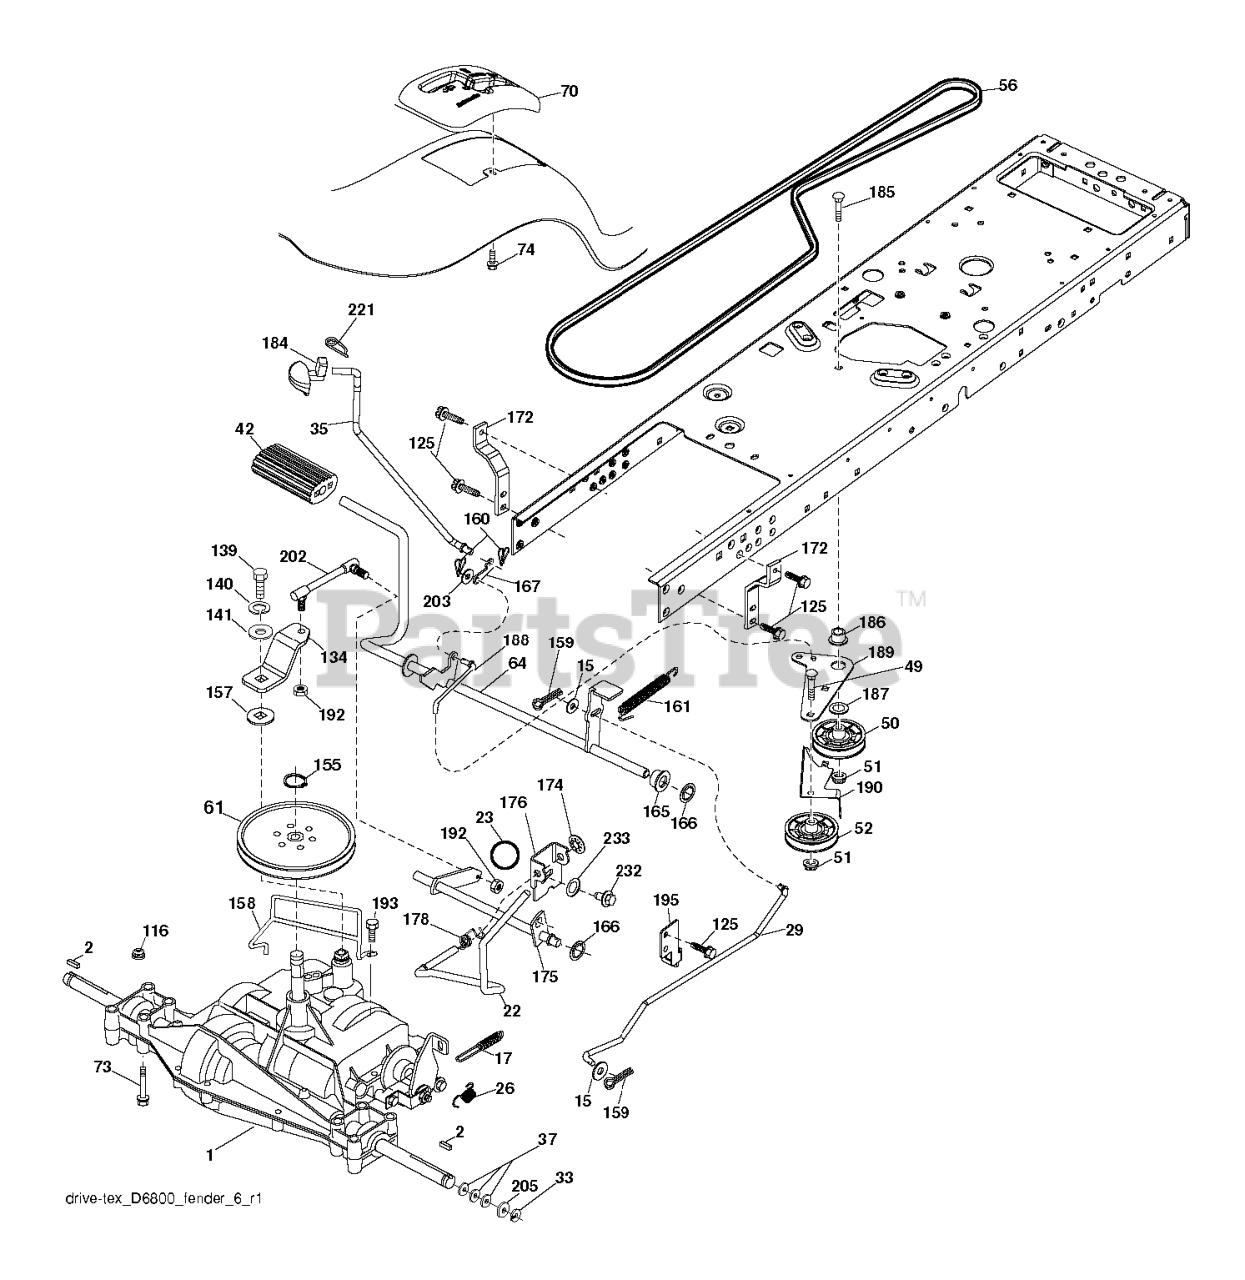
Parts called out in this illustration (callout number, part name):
2	SQUARE KEY
15	WASHER
17	SPRING.BRAKE.PEERLESS.TEX
22	ROD.SHIFT.FENDER.TLT.2006
23	KNOB.DUCKHEAD.1/2
26	SPRING.BRAKE.RTN.GR.DR
29	ROD.BRAKE.PEERLESS
35	ROD.CNTRL.PARK.PREDATOR.LT.TEX
42	PEDAL COVER T
50	IDLER.FLAT.910.OFFSET
51	NUT LOCK FLG 3/8-16 UNC
52	IDLER.V-GROOVE.910.OFFSET
56	V-BELT.TRACTOR.DRIVE.P
64	SHAFT.ASM.PEDAL.BRAKE.
70	CONSOLE ASM.STL.6SP.ROS.TEX.GR
73	BOLT HEX 5/16-18 GR 5
74	SCREW.HI-LO.CONSOLE
116	NUT LOCK HEX FLANGE 5/16-18
125	SCREW
134	ARM.SHIFT.
139	BOLT 1/4-28X3/4
140	LOCKWASHER
155	RETAINING RING LT
157	WASH-SHFT PLT LT
158	KEEPER.PMS.18/20.D4365
159	COTTER PIN
160	RETAINER CLIP
161	SPRING, RETURN LT
162	SPACER.TRANSAXLE.18&22
165	BUSHING.SHAFT.BRAKE.HAND
166	NUT.PUSH.625.2006
167	LATCH.BRAKE.SPRING
172	STRAP.TRQ.LH.GEAR.DRIV
174	NUT.PUSH.500.2006
175	SHAFT.ASM.SHIFT.
176	ARM.CLEVIS.ROD.SHIFT
178	SPRING.SHIFT.GT2006
184	HANDLE PARKING BRAKE
186	SPACER.RETAINER
187	WASHER 12/32X2X10GA
188	RP.LINK.CLUTCH.GROUND.DRIVE
189	BELLCRANK.GROUND.DRIVE.TEX.
190	KEEPER.BELLCRANK.DRIVE
192	NUT LOCK CENTER 1/4 -28 FNTHD
193	SCREW 5/16"
195	BRKT.ROD.BRAKE.PEERLES
202	LINK.TRANSAXLE.D6800.18/20"TEX
203	WASHER
221	RETAINER.SPRING.CLIP.H
232	BOLT FIN HEX 7/16-14 X 1
233	WASHER SERRATED
